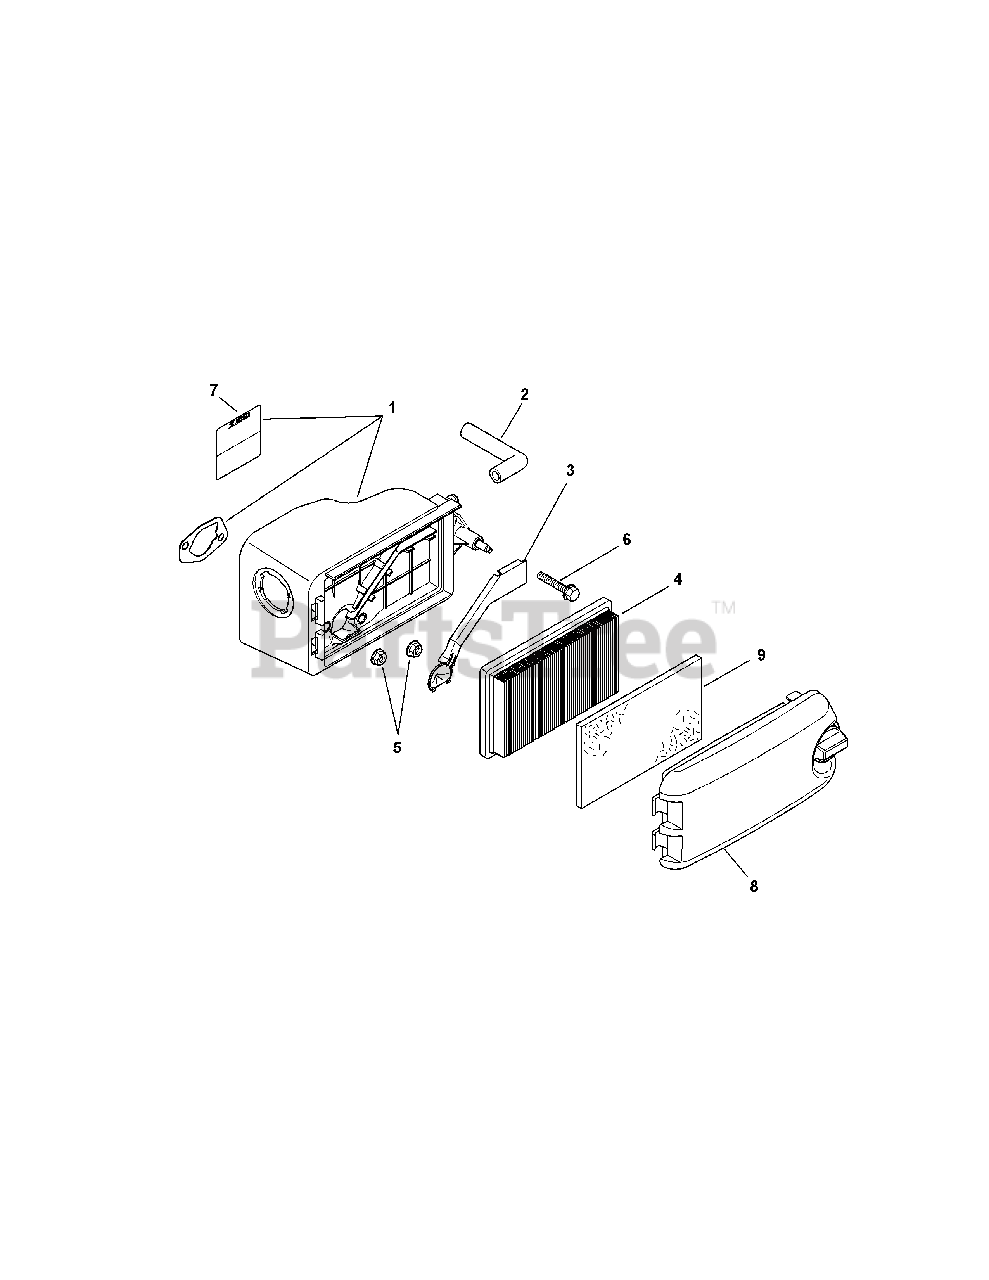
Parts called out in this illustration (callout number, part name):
1	Kit, Air Cleaner Base (Inc. Air Cleaner Base Gasket)
2	Breather Hose
3	Cover, A/C Base (Breather Gas)
4	Air Cleaner Element
5	Nut, Hex Flange, M6
6	Screw, Hex Flange, M6
7	Nameplate, Service
8	Air Cleaner Cover
9	Carbon Pre-Filter Element
